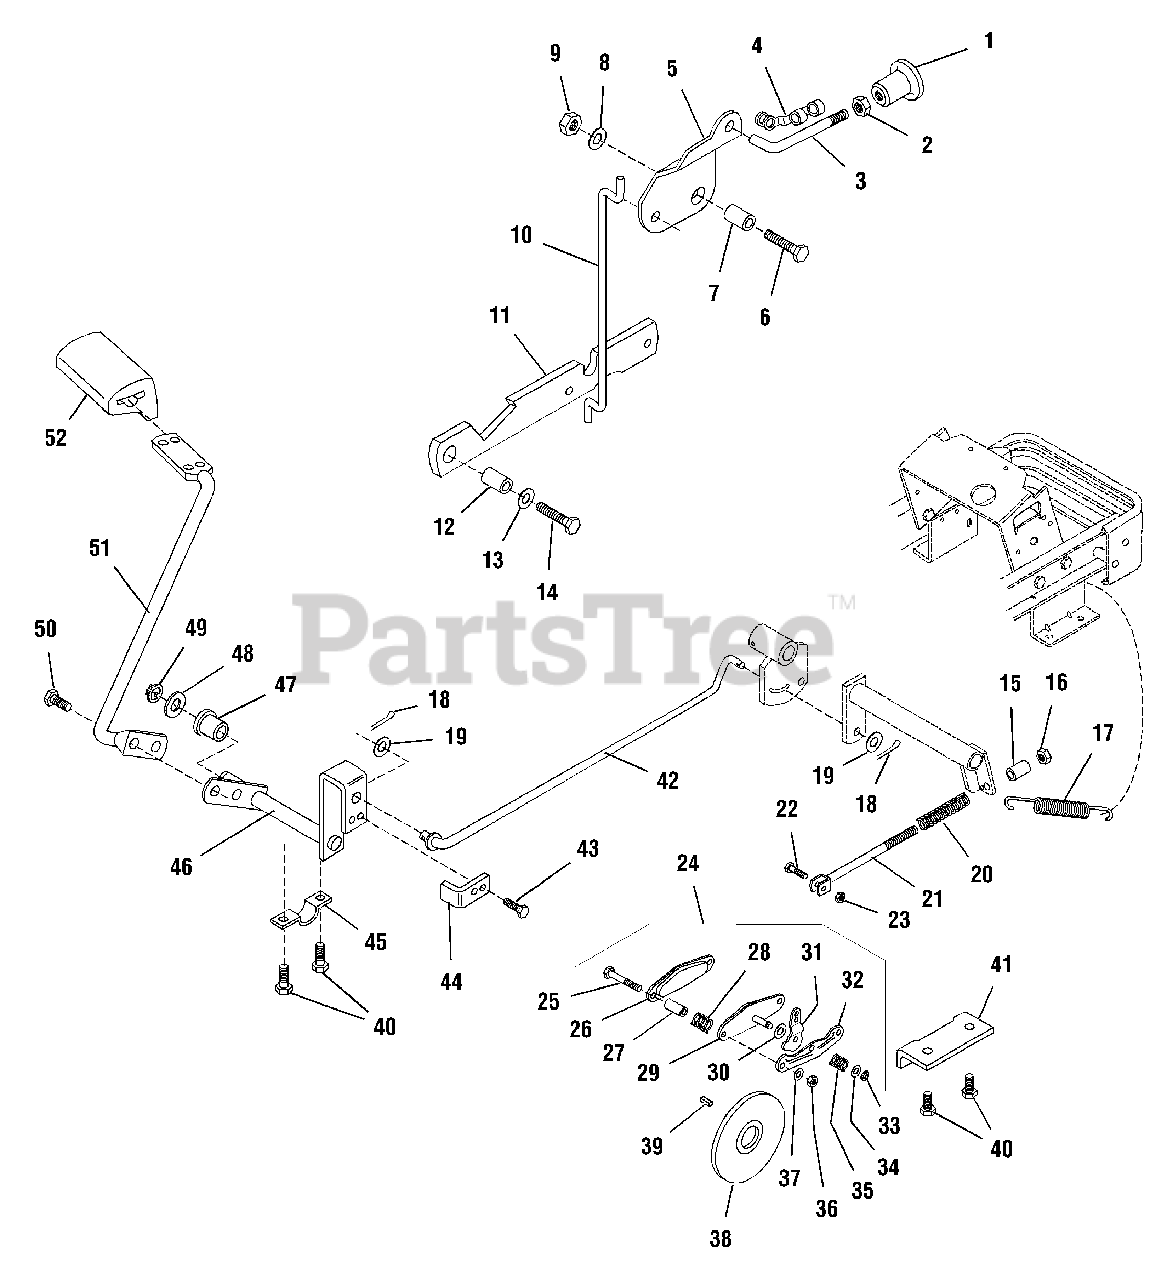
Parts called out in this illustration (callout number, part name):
1	KNOB, Parking Brake
2	NUT, Hex Lock, #10-24
3	ROD, Park Brake
5	BRACKET, Park Brake Pivot
6	CARRIAGE BOLT, 1/4-20 x 3/4
7	SPACER, .281 x 1/2 x .32 LG
8	WASHER, Plain, 1/4
9	NUT, Hex, Center Lock, 1/4-20
10	ROD, Park Brake
11	BRACKET, Park Brake
12	SPACER, .325 x 3/4 x .63
13	WASHER, Flat, 5/16
14	CAPSCREW, Hex Hd, Taptite, 5/16-18 x 1-1/4
16	NUT, Hex, Nylon Lock, 3/8-16
17	SPRING, Extension
18	PIN, Cotter, 1/8 x 3/4
19	WASHER, Plain, 3/8
20	SPRING, Compression
21	ROD ASSEMBLY, Brake
22	CAPSCREW, Hex Hd, 1/4-20 x 1
23	NUT, Hex, Nylon Lock, 1/4-20
24	CALIPER ASSEMBLY, Brake
25	CAPSCREW, Hex Hd, 1/4-20 x 2
26	PAD, Brake, Outer
28	SPRING, Compression
29	PAD, Brake, Inner
32	BRACKET, Mounting
35	SPRING, Compression
36	NUT, Hex, 1/4-20
37	LOCKWASHER, 1/4
38	BRAKE, Disc
39	KEY, Woodruff, 3/16 x 3/4 #9
40	CAPSCREW, Hex Hd, Taptite, 5/16-18 x 3/4
41	BRACKET, Caliper Mtg.
43	RIVET, Pop, 3/16 x 7/16 lg
44	ACTUATOR, Switch
46	BRAKE ARM ASSEMBLY
48	WASHER, Plain, 3/4 x 1
49	CLIP RING, 3/4
50	CAPSCREW, Hex Hd, Taptite, 3/8-16 x 1
51	LEVER, Brake
52	PAD, Brake Pedal
